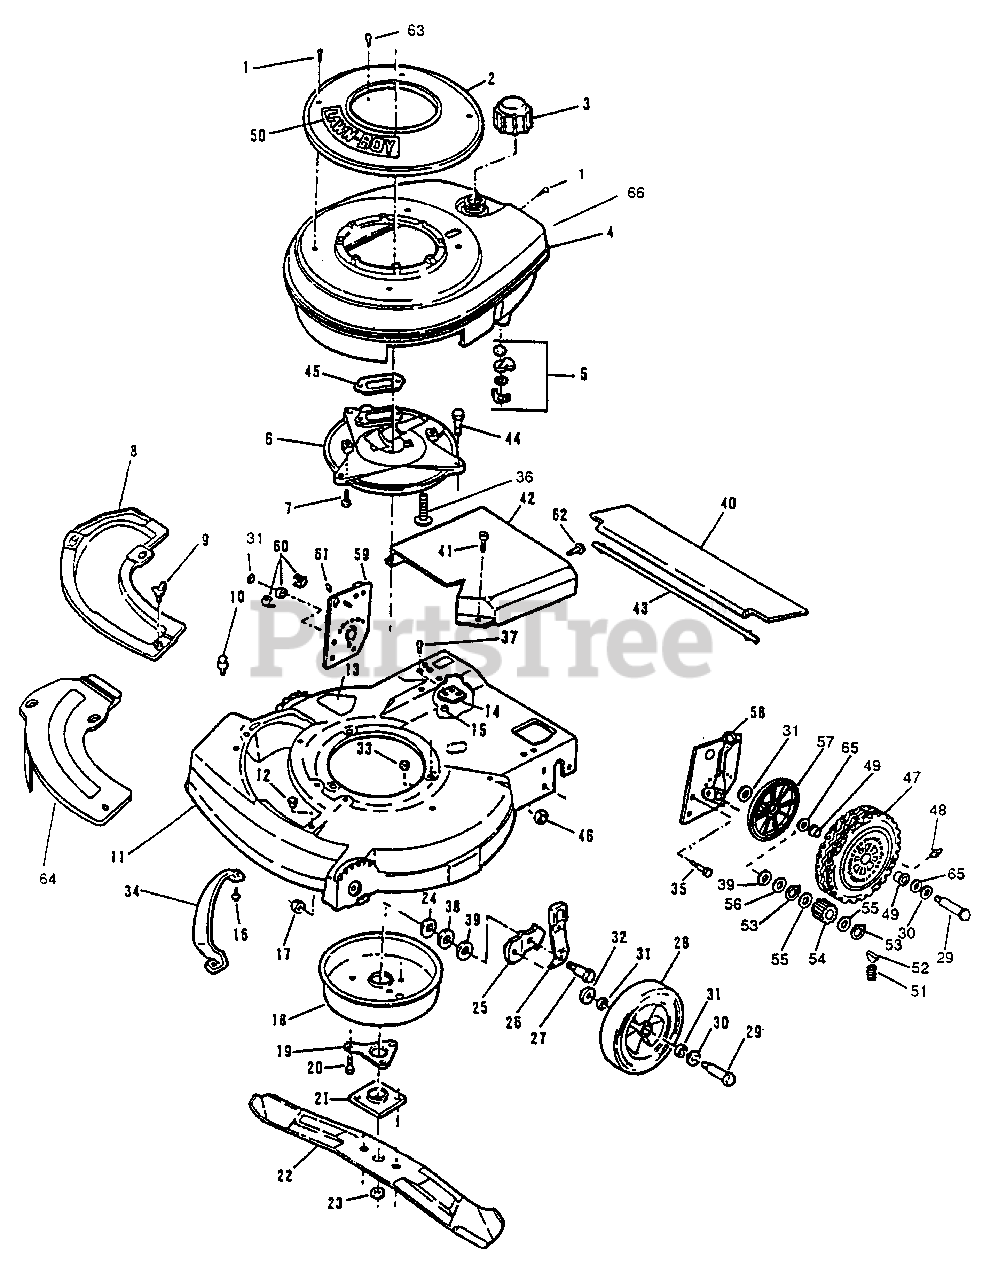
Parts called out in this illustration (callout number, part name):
1	Screw
2	Starter Base & Nut Assembly
3	Fuel Cap
4	Shroud-Engine (Inc. 5)
5	Fuel Shut-Off Assembly
6	Plate Muffler
7	Screw-Muffler Plate to Block
8	Cover Plate
9	Wing Screw
10	Screw-Plate & Chute Mounting
11	Housing Assembly (Inc. 12-13)
12	Grommet
13	Decal-Blade Contact Warning
14	Bolster-Housing
15	Nut-Bolster to Housing
16	Screw
17	Nut
18	Muffler Cover Assembly
19	Support-Crankshaft
20	Screw-Muffler to Muffler Plate
21	Collar & Plate Assembly
22	Blade-21"
23	Nut-Blade
24	Washer
25	Bracket-Wheel Height Adjust
26	Knob & Spring Assembly
27	Bolt-Shoulder
28	Wheel-Front
29	Bolt-Wheel
30	Washer-Flat
31	Washer-Felt
32	Washer
33	Nut-Muffler Plate to Housing
34	Toe Bar
35	Screw-Handle Bracket
36	Screw-Muffler Plate To Block
37	Screw-Bolster to Housing
38	Washer-Shim-Wheel Height Adjust Bracket
39	Washer-Shim-Wheel Height Adjust Bracket
40	Shield-Trailing
41	Screw-Drive Cover Mounting
42	Cover-Drive
43	Rod-Trailing Shield
44	Screw-Muffler Plate to Housing
45	Gasket-Exhaust
46	Locknut-Hdl. Brkt. to Housing
47	Rear Wheel (Inc. 48-49)
48	Lube Fitting
49	Bushing-Wheel
50	Applique-Starter Base
51	Spring
52	Key
53	Retaining Ring
54	Pinion
55	Spacer
56	Washer
57	Cover-Rear Wheel
58	Height Adjuster Assembly-L.H. (Inc. 60-61)
59	Height Adjuster Assembly-R H. (Inc. 60-61)
60	Bearing & Retainer Assembly
61	Fitting
62	Screw
63	Screw-Starter Mounting
64	Mulch Plate Accessory
65	Washer-Felt
66	Decal-Fuel Mix
